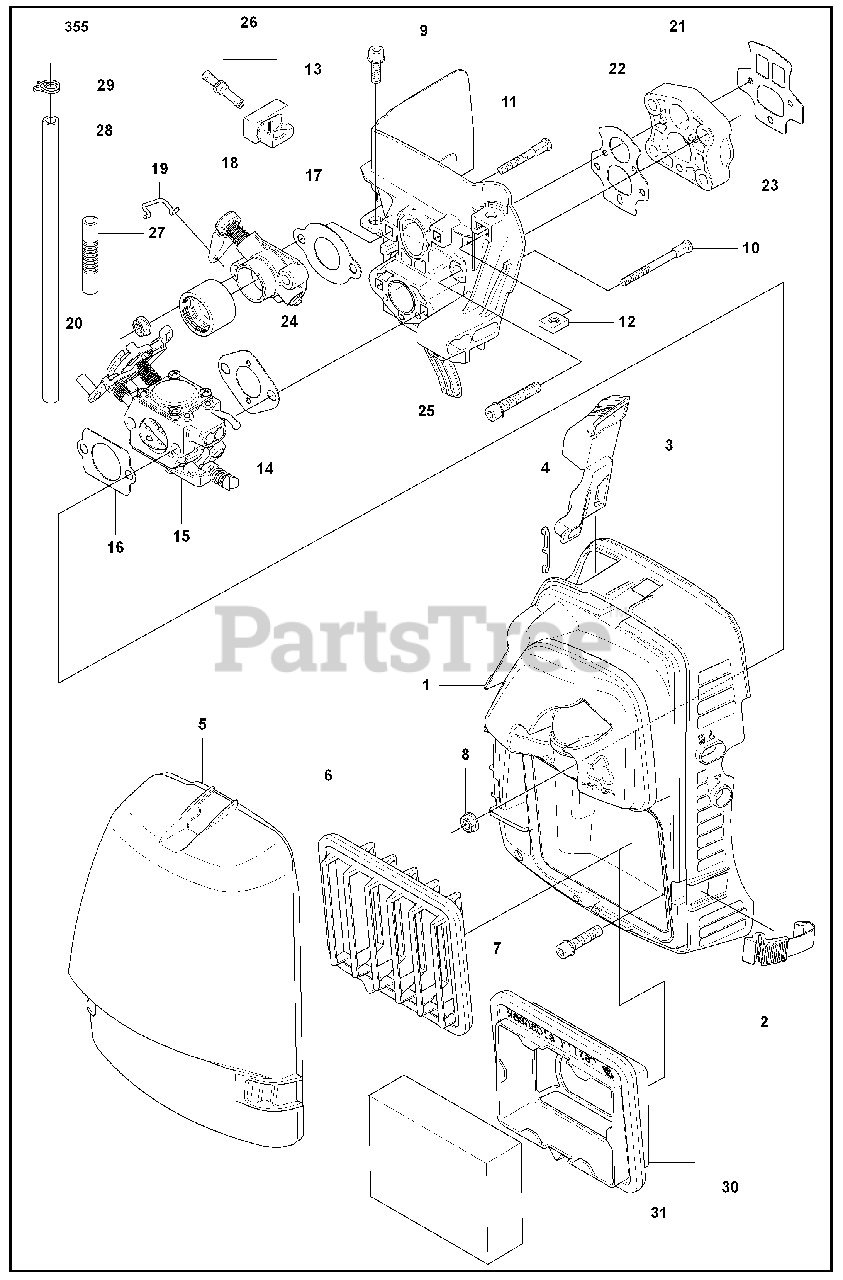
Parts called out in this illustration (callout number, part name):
1	FILTER HOLDER
3	CHOKE CONTROL
5	FILTER COVER
6	FILTER
9	INSULATION WALL
14	%GASKET
15	CARBURETOR WT-814A
18	VALVE HOUSING
23	RP GASKET
24	INLET PIPE
25	SCREW IHSCFM
27	SUCTION HOSE
28	RP FUEL HOSE
29	HOSE CLAMP
30	FILTER
31	FILTER
